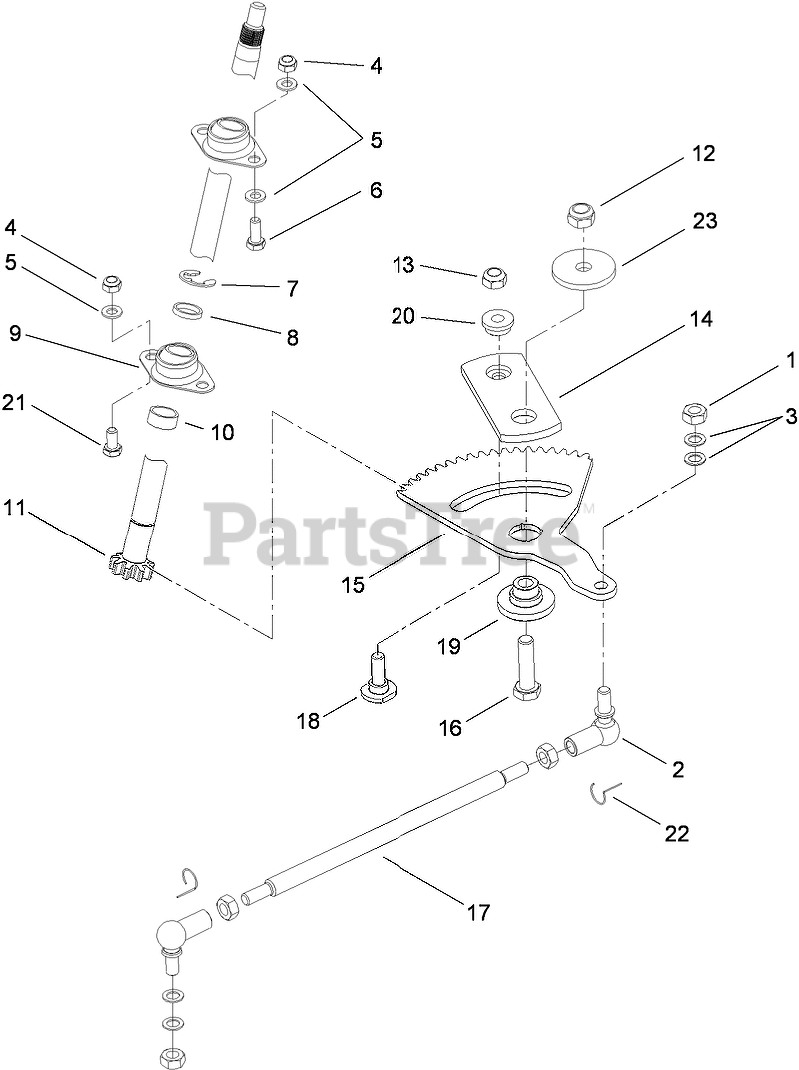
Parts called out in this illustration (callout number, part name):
1	NUT-LOCK, NI
2	JOINT-BALL, ANGLE
3	Washer
4	NUT-LOCK, NI
5	WASHER-PLAIN
6	SCREW-HH
7	CLIP-SPRING
8	SPACER-UPPER
9	BEARING-SPHERICAL
10	SPACER-LOWER
11	Shaft-Steering
12	NUT-LOCK
13	NUT-LOCK, NI
14	Plate-Steering
15	GEAR-SECTOR
16	SCREW-HH
17	LINK-DRAG
18	Bolt-Shoulder
19	Pivot-Steering
20	Bushing
21	SCREW-HH
22	Stirrups-Locking
23	WASHER
